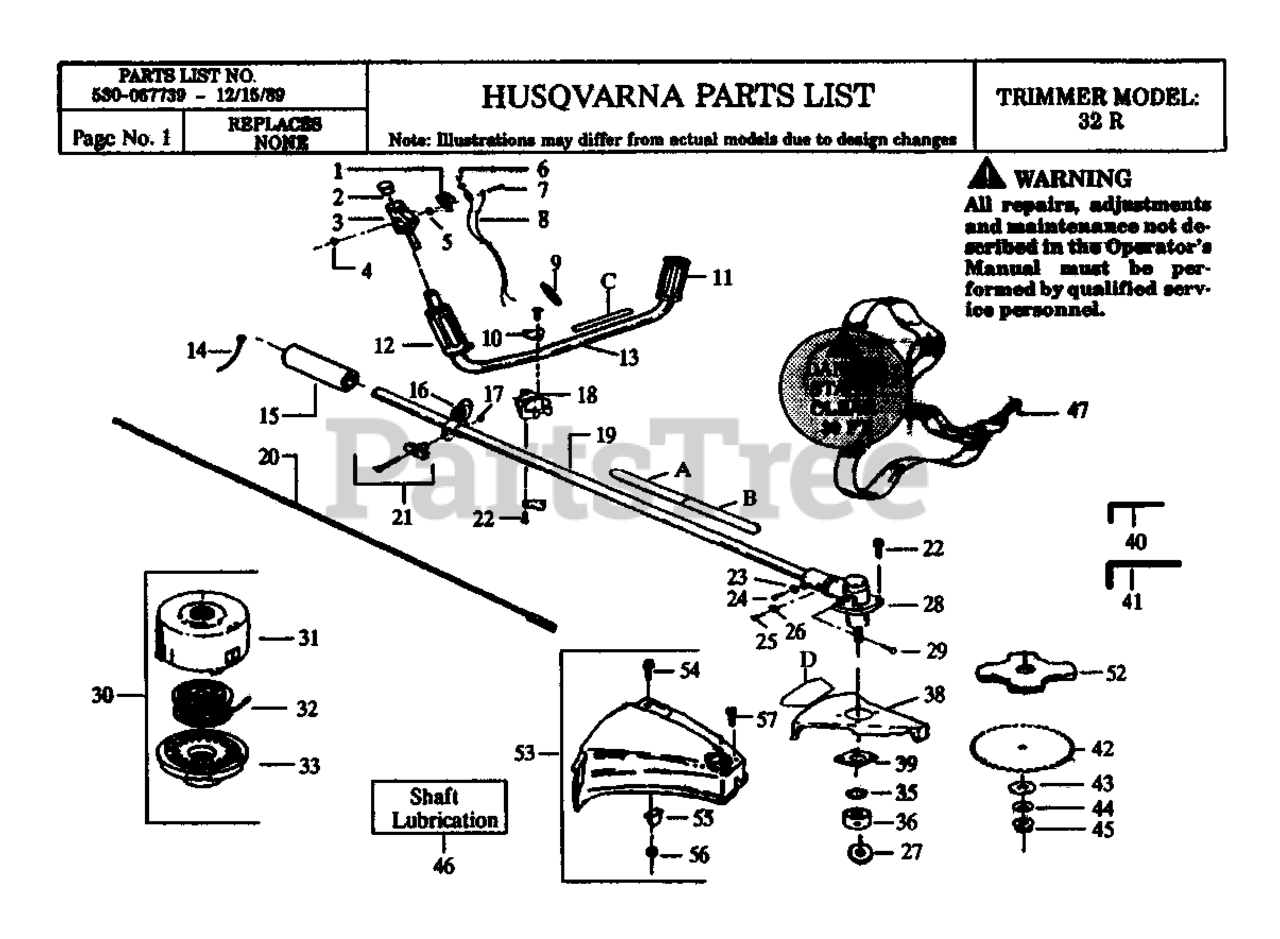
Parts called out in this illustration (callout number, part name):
1	Kill Switch Bracket
2	CAP-HANDLEBAR
3	Throttle Lever Ass'y. w/ Lock
4	LOCKNUT-HEX 10-24
5	SPACER-REMOTE KILL SWIT
6	NUT SWITCH MOUNT
7	SCREW 6-19 X 3/8 (PLAST
8	Wire Harness Ass'y
9	TERMINAL LOCK
10	BRACKET-HANDLEBAR
11	HANDLEGRIP
12	Handguard Grip
13	H'BAR-OFFSET (W/DECAL)
16	ASSY-CLAMP HARNESS
18	Handlebar Clamp
19	Drive Shaft Housing
20	SHAFT-FLEX (57").
21	KIT "T" HANDLE
23	LOCKWASHER-LOCATOR-TYPE 2
24	SCREW-10-24 X 7/16 (HEX
25	SCREW-1/4-20X1 HEX SOC
26	LOCKWASHER
27	WASHER-GRASS
28	GEAR BOX ASSY/TYPE 1
30	Cutting Head Ass'y.
31	ASSY-HUB SHAFT & BAL AR
32	Spool w/Line
39	PLATE-SHIELD RETENTION
40	HEX KEY
41	HEX KEY 3/16"
42	Brush Blade -- 8"
43	WASHER-FLAT.
44	WASHER-SPRING BELLEVIL
45	NUT-FLANGE (LH)
46	GREASE-1/2 FL. OZ.
47	STRAP-SHOULD.W/WARNING
52	Weed Blade
53	KIT-SHIELD
55	LIMITER-LINE
56	LOCKNUT-(10-24)
57	SCREW 1/4-10 PLASTITE
A	Decal-Shaft Warning (Upper)
D	DECAL-BLADE DIRECT(FR/E
B	Decal-Shaft Warning (Lower)
C	Decal-Handlebar Warning
